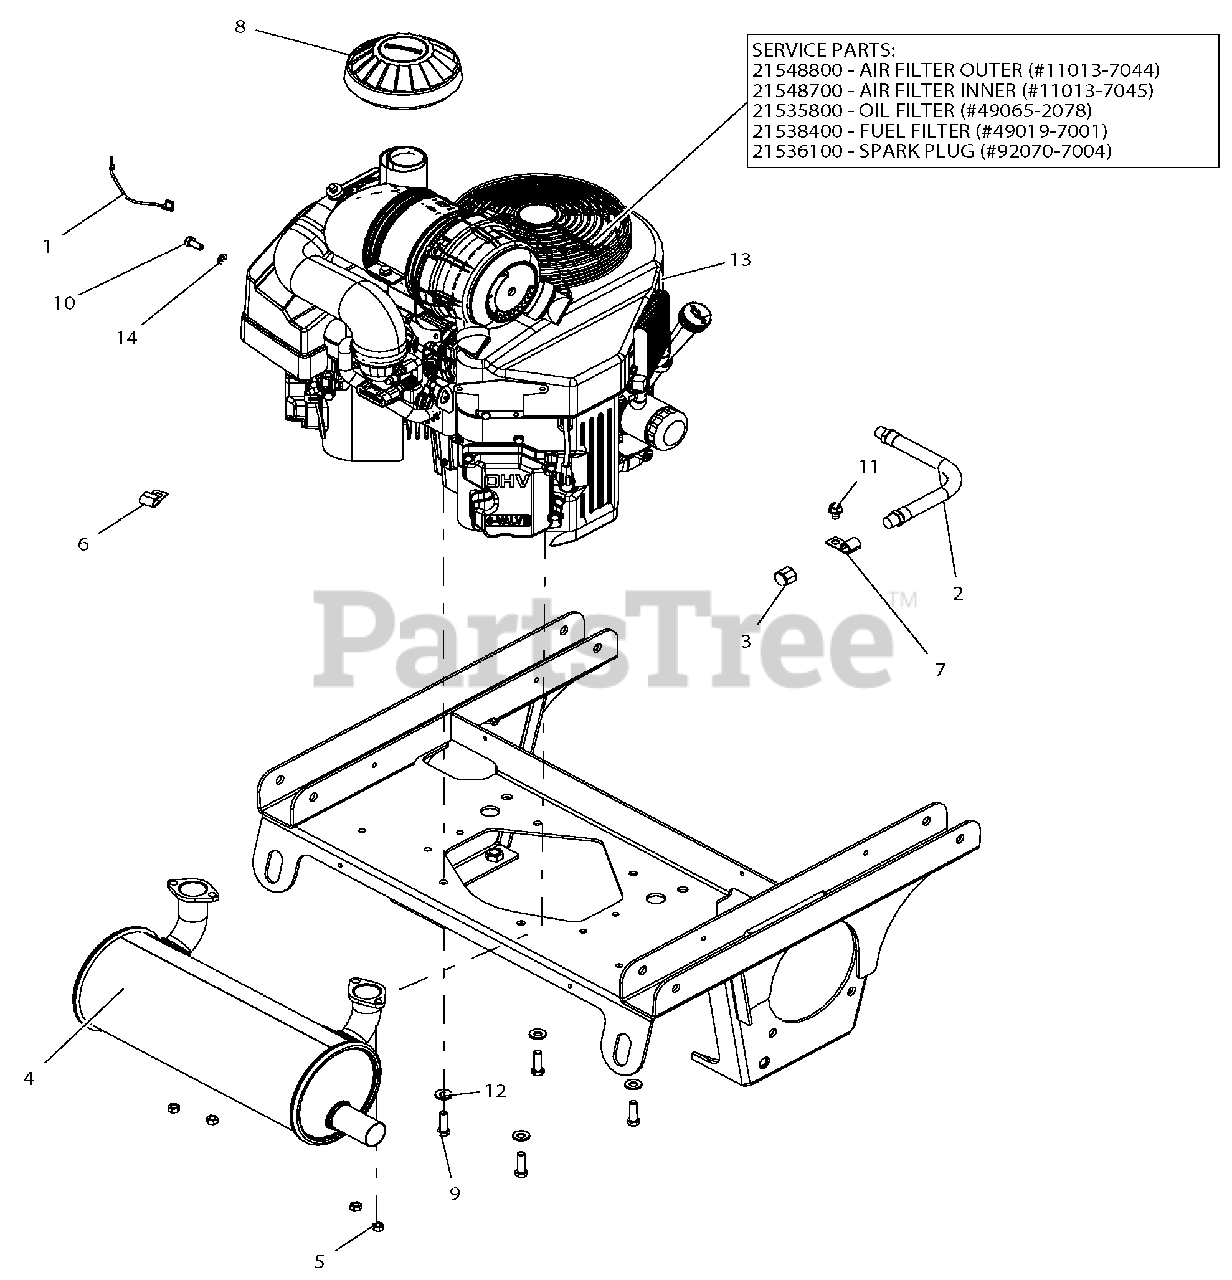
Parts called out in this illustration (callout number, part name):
1	LEAD - STARTER SOLENOID
2	HOSE, HYD .38-11-0K M6N0-M6N0
3	PIPE, CAP 3/8 NPT FEMALE
4	MUFFLER - 34HP KAWASAKI VERT
5	NUT-LK-TOP M8-1.25 YWZC
6	CLAMP, J
8	CAP, AIR CLEANER INTAKE (2")
9	BLT-HEX .38-16X1.25 GR5 YWZC NYTORQ
10	@BLT-HEX M8-1.25X20 YWZC
11	SCR-TAP .38-16X.50 HWH TR YWZ
12	WSHR, 3/8" SPRING DISC
13	ENGINE, KAWASAKI FX921
14	WSHR-LK .31X.078 REG YWZC
